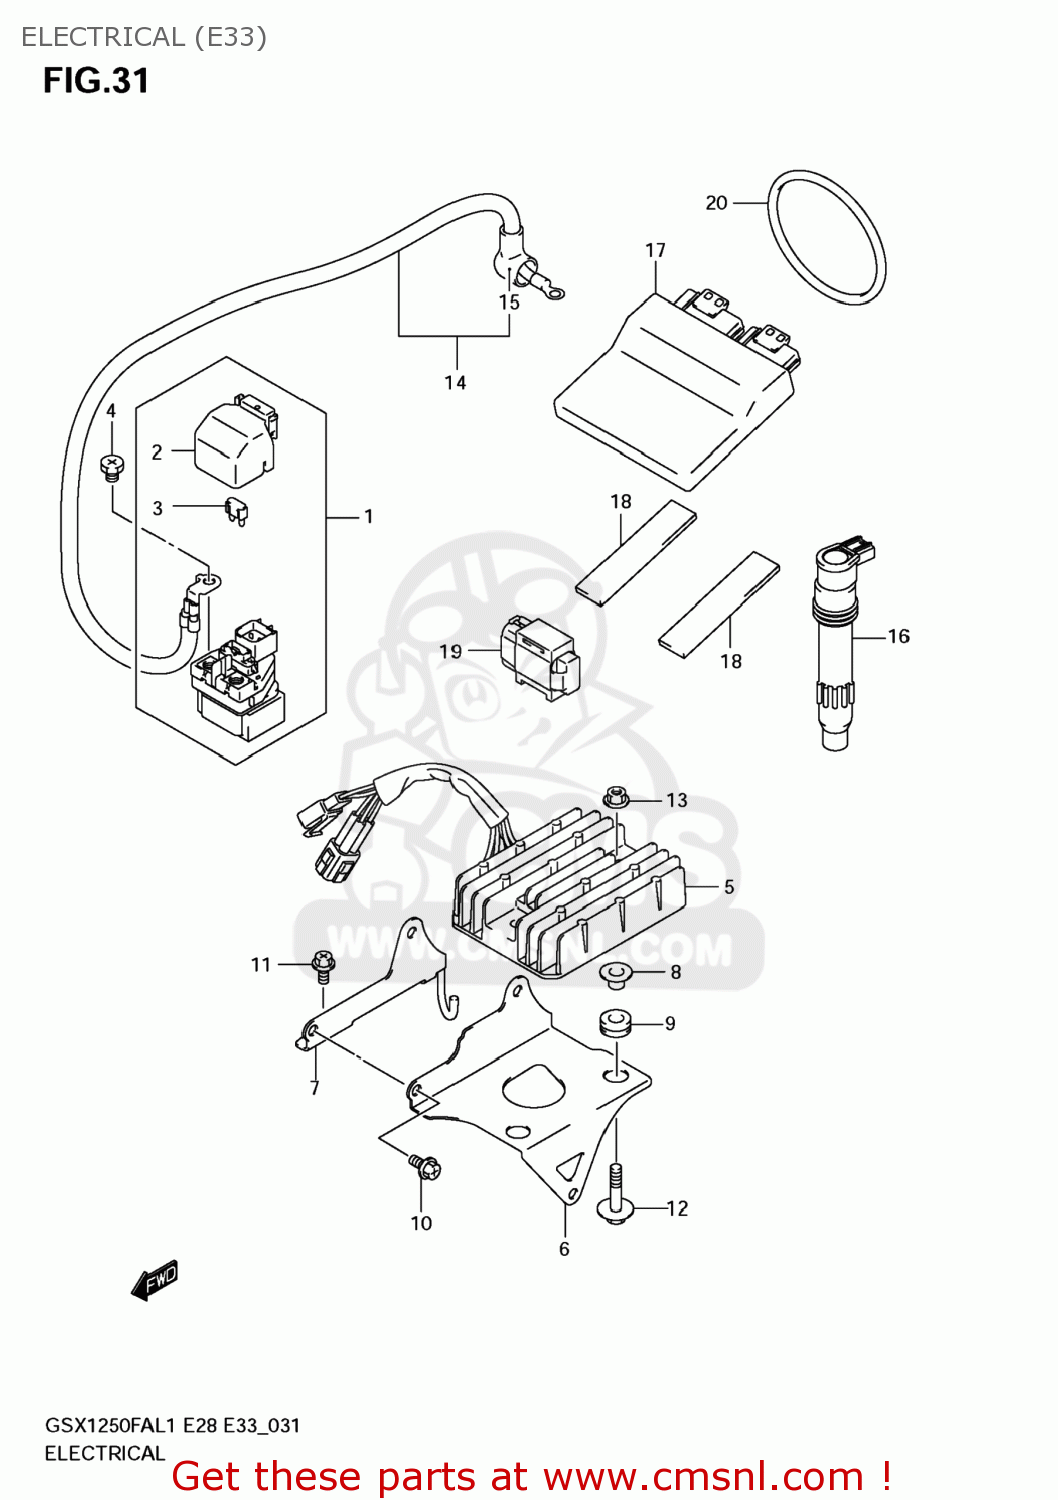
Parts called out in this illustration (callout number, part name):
1	RELAY ASSY,STARTING MOTOR
2	COVER
3	FUSE(30A)
4	SCREW(6X8)
5	RECTIFIER ASSY
6	BRACKET,RECT FTG NO.1
7	BRACKET,RECT FTG NO.2
8	SPACER(6.2X8.4X6.9)
9	CUSHION
10	BOLT
11	BOLT
12	BOLT(6X20)
13	NUT
14	WIRE,STARTER MOTOR LEAD
15	CAP,STARTER MOTOR
16	COIL ASSY,IGNITION
17	CONTROL UNIT,FI
18	PROTECTOR(20X90)X2
19	SENSOR ASSY,FUEL CUT
20	O RING(D:3.53,ID:69.44)
